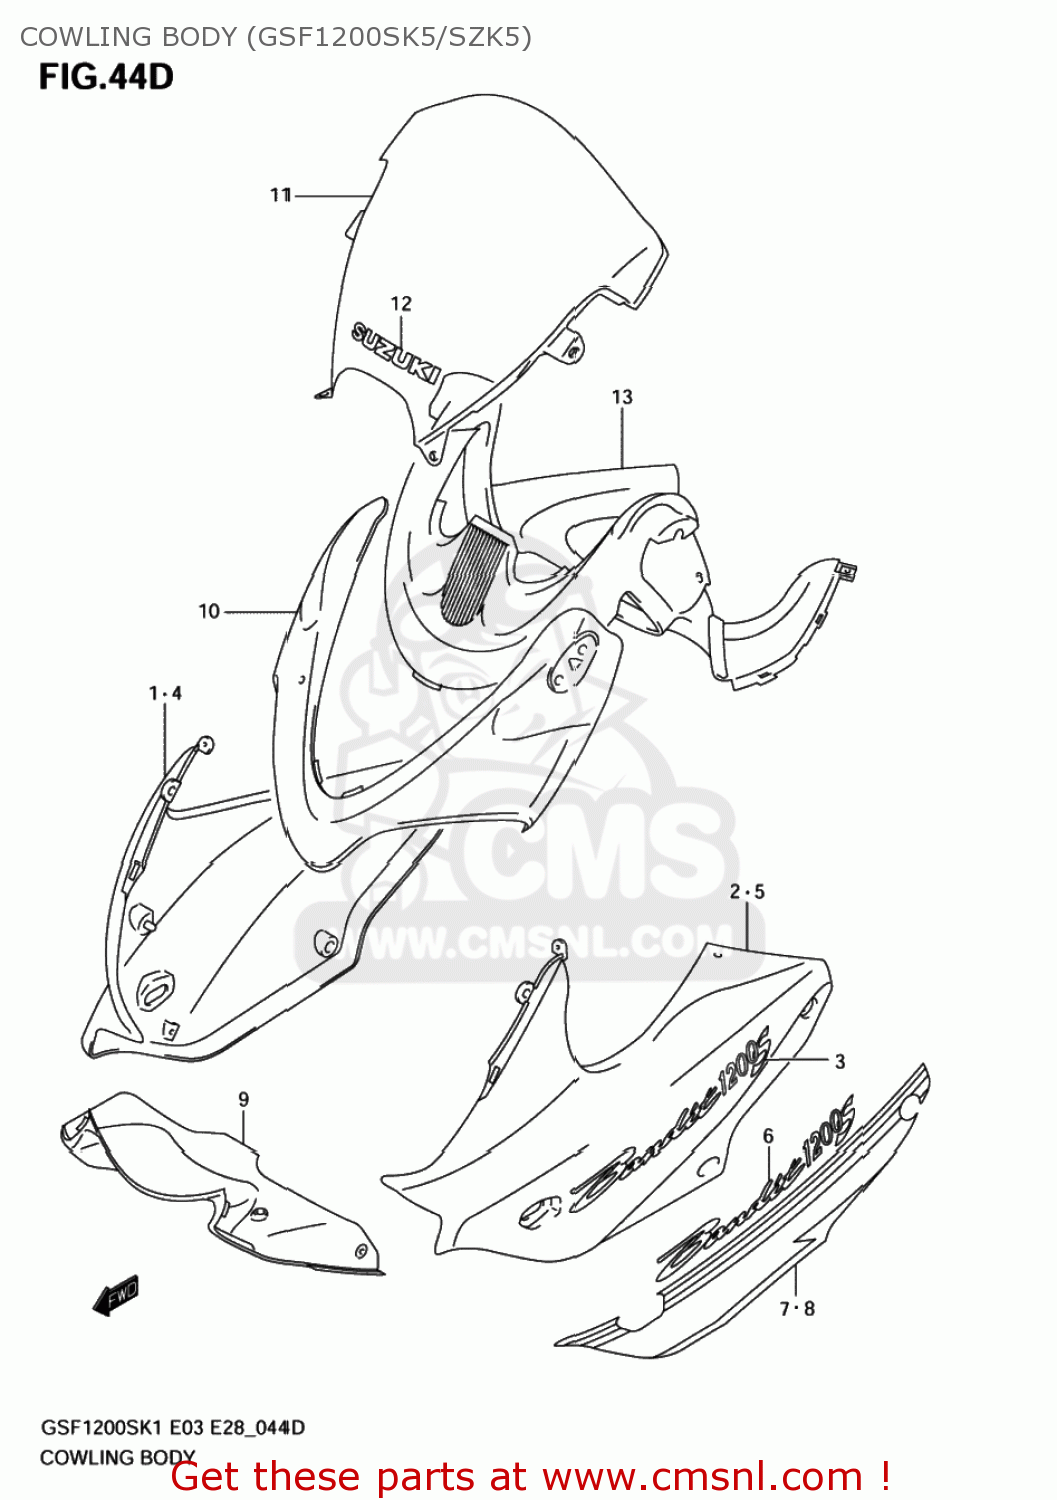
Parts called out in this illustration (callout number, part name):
1	COWLING ASSY,SIDE,R
2	COWLING ASSY,SIDE,L
3	EMBLEM,COWLING SIDE
4	COWLING ASSY,SIDE,R
5	COWLING ASSY,SIDE,L
6	EMBLEM,SIDE
7	TAPE,COWL SIDE,R
8	TAPE,COWL SIDE,L
9	COWLING,CTR(BLUE)
10	COWLING,FR
11	WINDSCREEN ASSY(SILVER)
12	EMBLEM,SUZUKI
13	PANEL,METER
